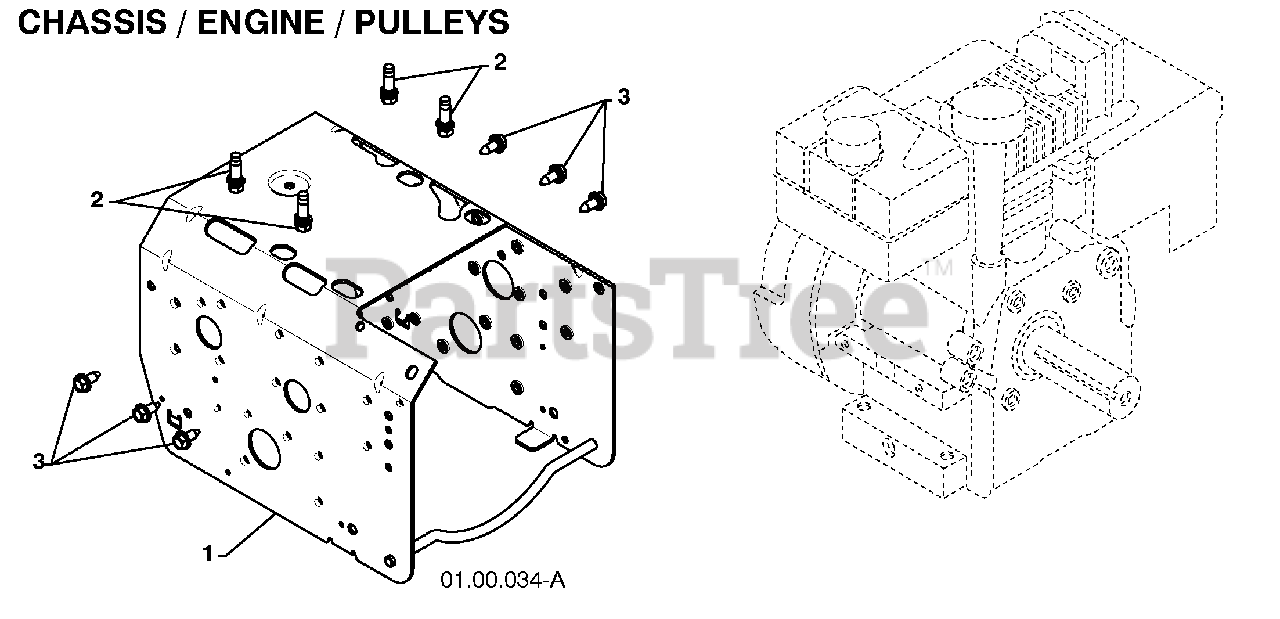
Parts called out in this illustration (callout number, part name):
1	FRAME
2	BOLT 3/8-16
3	SCREW 5/16-18 X .750
